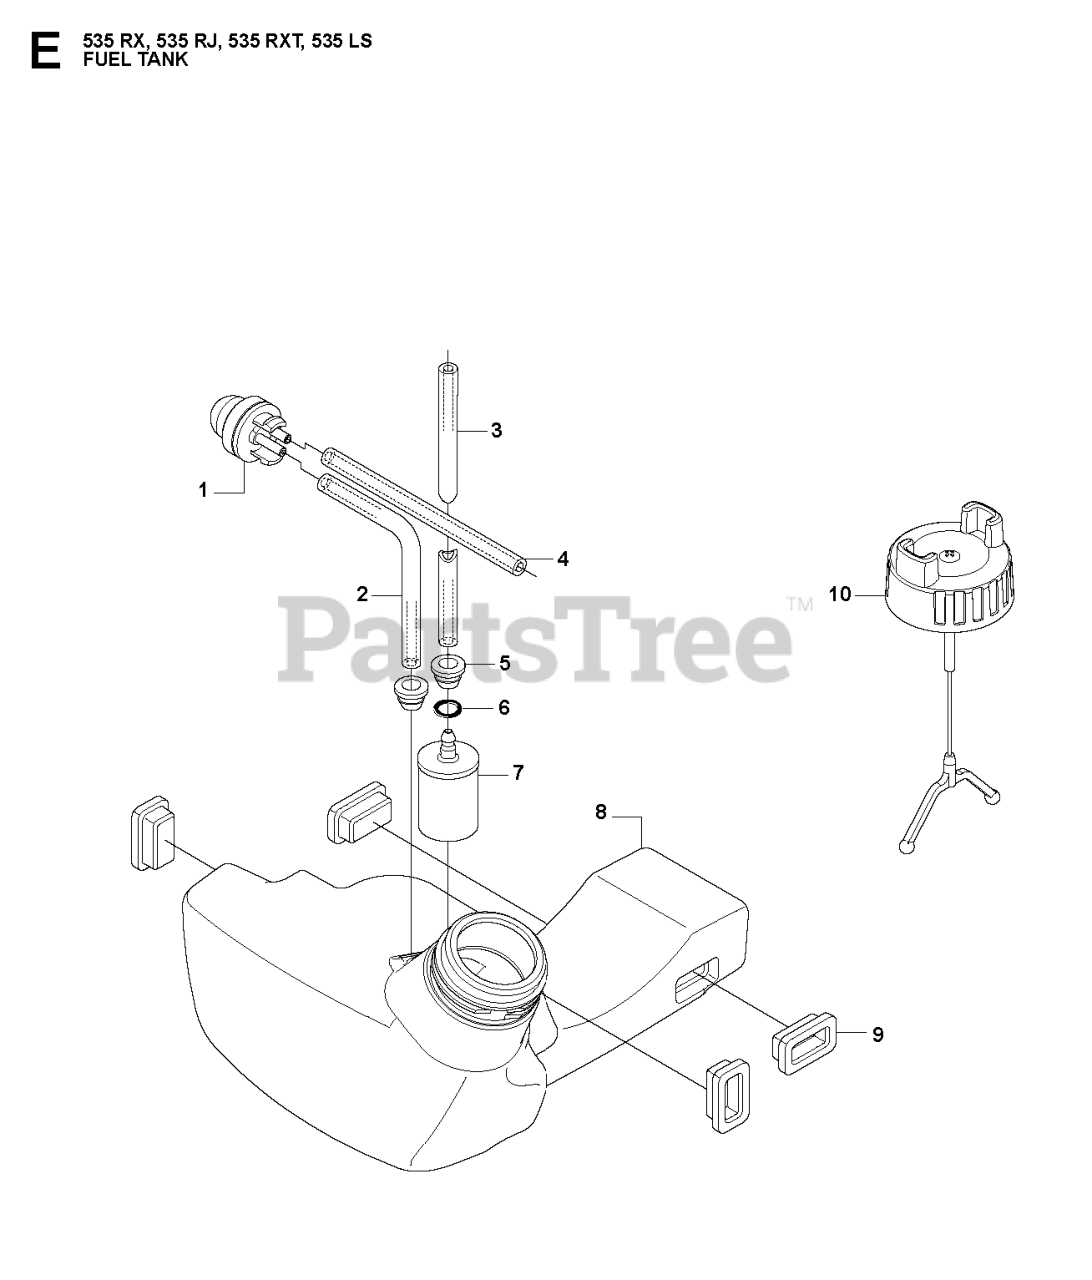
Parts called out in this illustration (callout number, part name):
1	AIR PURGE BUBBLE
5	FUEL TANK BUSHING
7	RP FUEL FILTER
